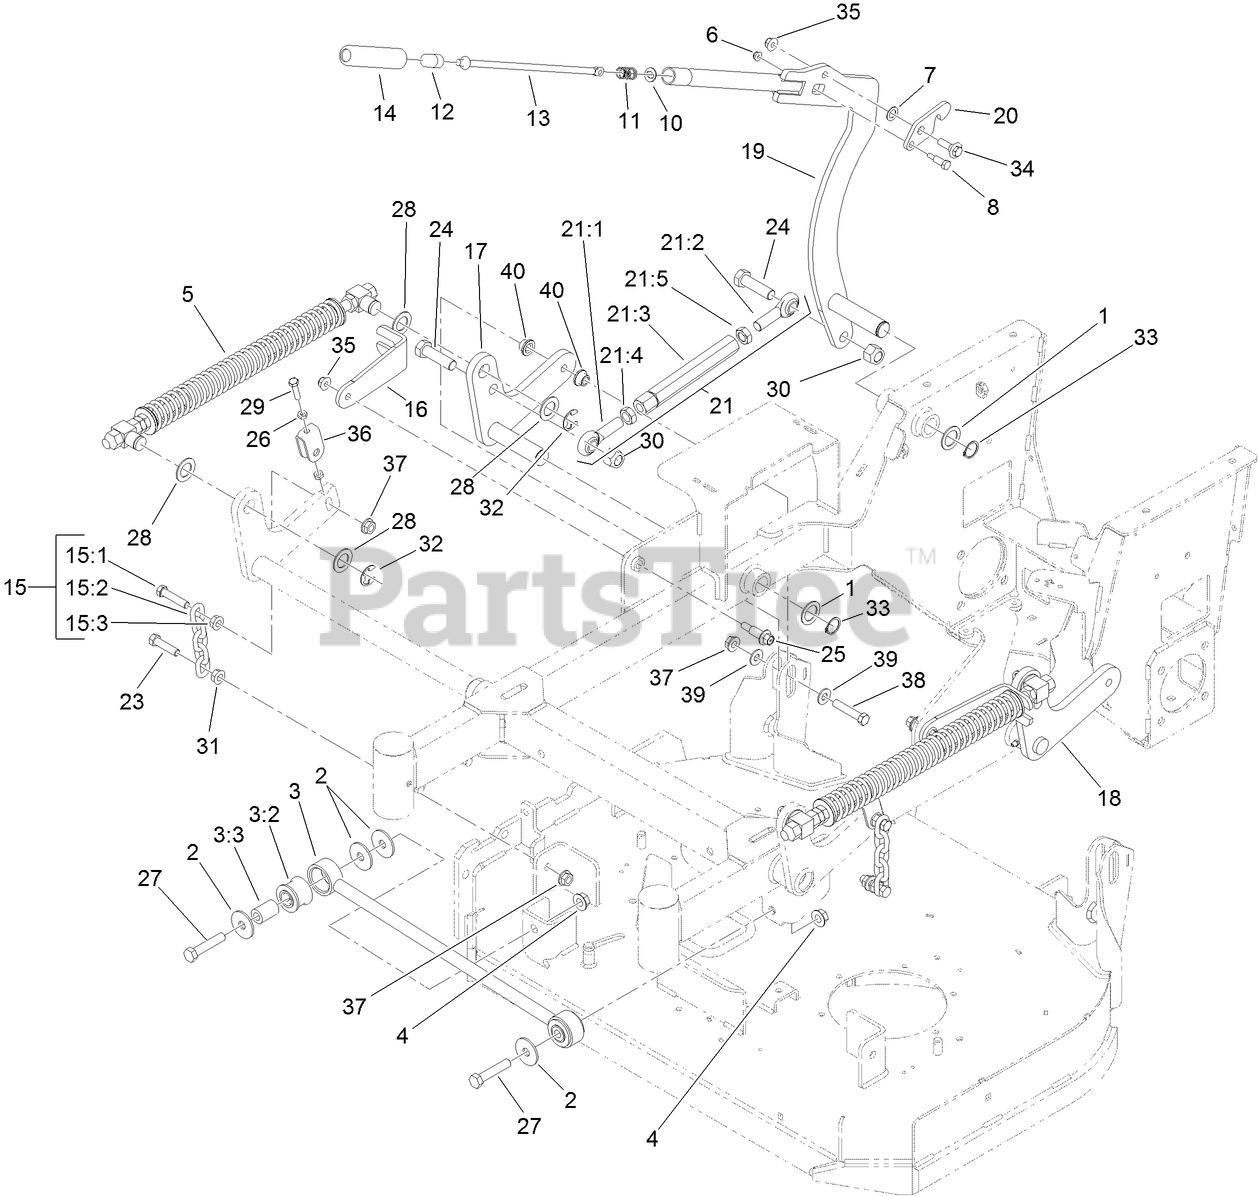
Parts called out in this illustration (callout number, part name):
1	WASHER-SPACER
2	WASHER-THRUST
3	PANHARD ROD ASM
3:2	BUSHING-SUSPENSION, RUBBER
3:3	SPACER
4	NUT-HF
5	DECK LIFT SPRING ASM
6	NUT-HF
7	WASHER
8	BOLT-SHOULDER
10	WASHER-SPECIAL
11	SPRING-COMPRESSION
13	ROD-LATCH
15	DECK LIFT CHAIN ASM
15:1	CHAIN-LIFT, DECK
15:2	SCREW-HH
15:3	NUT-HF
16	BRACKET-FORK
17	ARM-LIFT, RH
18	ARM-LIFT, LH
19	ARM-LIFT, HOC
20	LATCH-HOC
21	DECK LIFT LINK ASM
21:1	BALLJOINT-SPHERICAL
21:2	BALLJOINT-SPHERICAL
21:3	LINK-LIFT, DECK
21:4	NUT-JAM
21:5	NUT-JAM
23	SCREW-HH
24	SCREW-HH
25	BOLT-SHOULDER
26	NUT-JAM
27	SCREW-HH
28	WASHER-FLAT
29	SCREW-HH
30	NUT-LOCK, NI
31	NUT-HF
32	RING-RETAINING, EXT
33	RING-RETAINING
34	SCREW-SHOULDER, HWH
35	NUT-HF, NI
36	YOKE-ADJUST, DECK
37	NUT-HF
38	SCREW-HH
39	WASHER-FLAT
40	BUSHING-FLANGED
